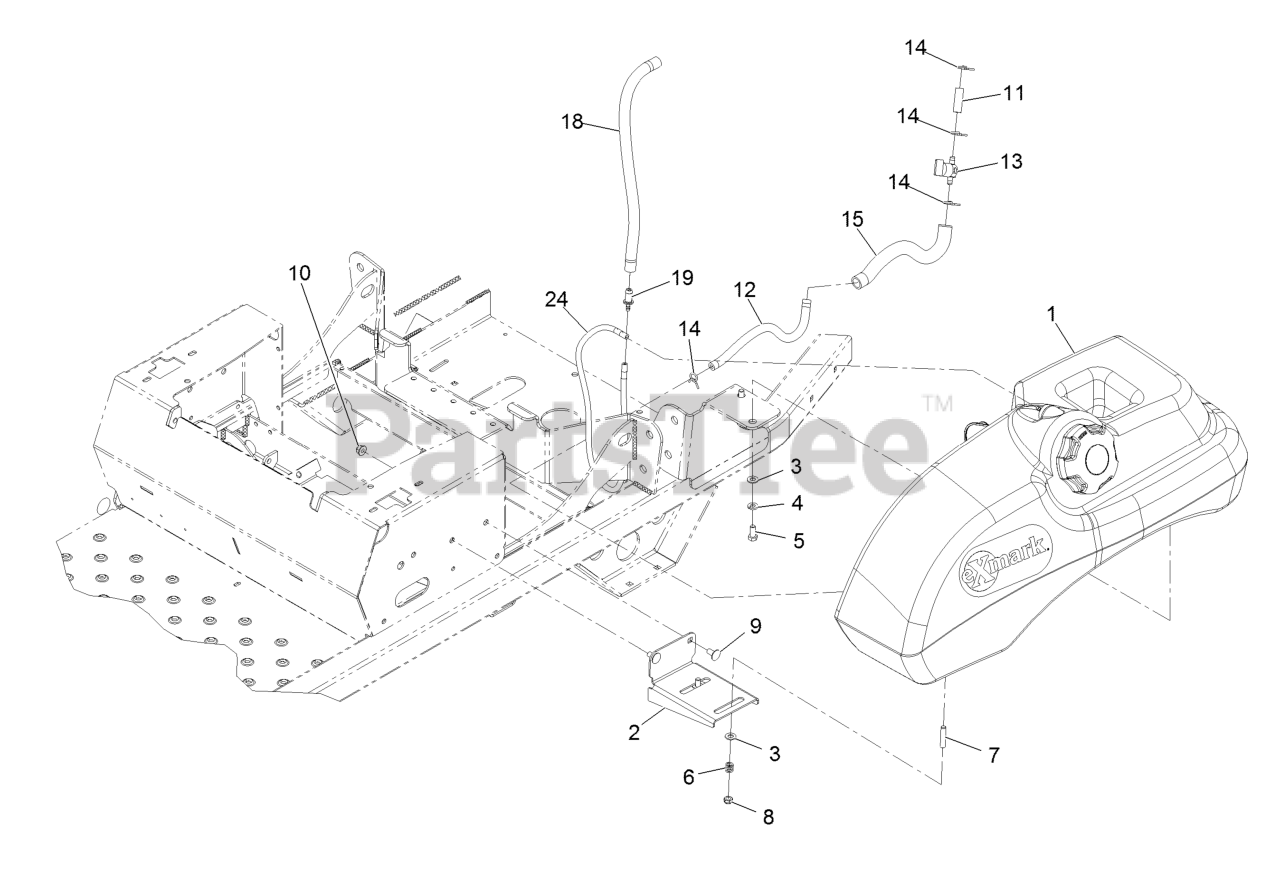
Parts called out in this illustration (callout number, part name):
1	ASM-FUEL TANK
2	BRACKET-TANK AND FENDER
3	WASHER-PLAIN
4	WASHER-LOCK
5	SCREW-HH
6	SPRING-TANK, FUEL
7	STUD
8	NUT-LOCK, NI
9	SCREW-CARR
10	NUT-HF, NI
11	HOSE-FUEL
12	HOSE-FUEL
13	VALVE-FUEL
15	CONDUIT-FUEL LINE
18	HOSE-FUEL
19	FITTING-ORIFICE, STRAIGHT
24	HOSE,EMISSIONS
